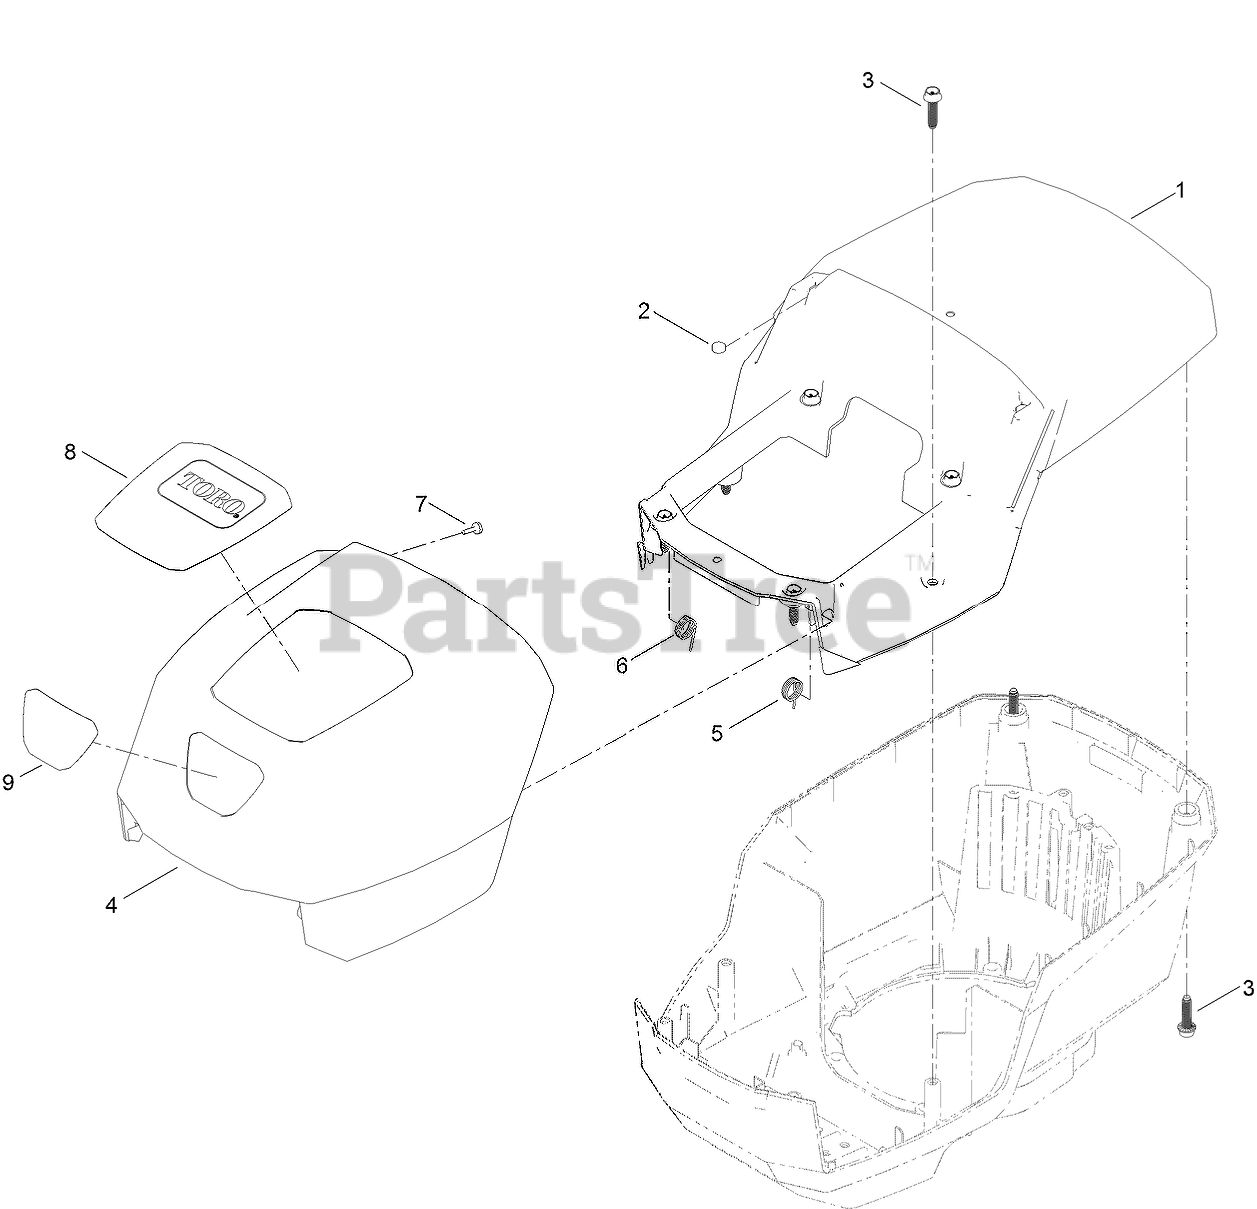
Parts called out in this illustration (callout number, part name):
1	SHROUD-UPPER
2	MAGNET
3	SCREW-FLANGE, PLASTIC
5	SPRING-LH
6	SPRING-RH
7	SCREW-PPH
8	DECAL-HOOD, TOP
9	DECAL-HOOD, FRONT
